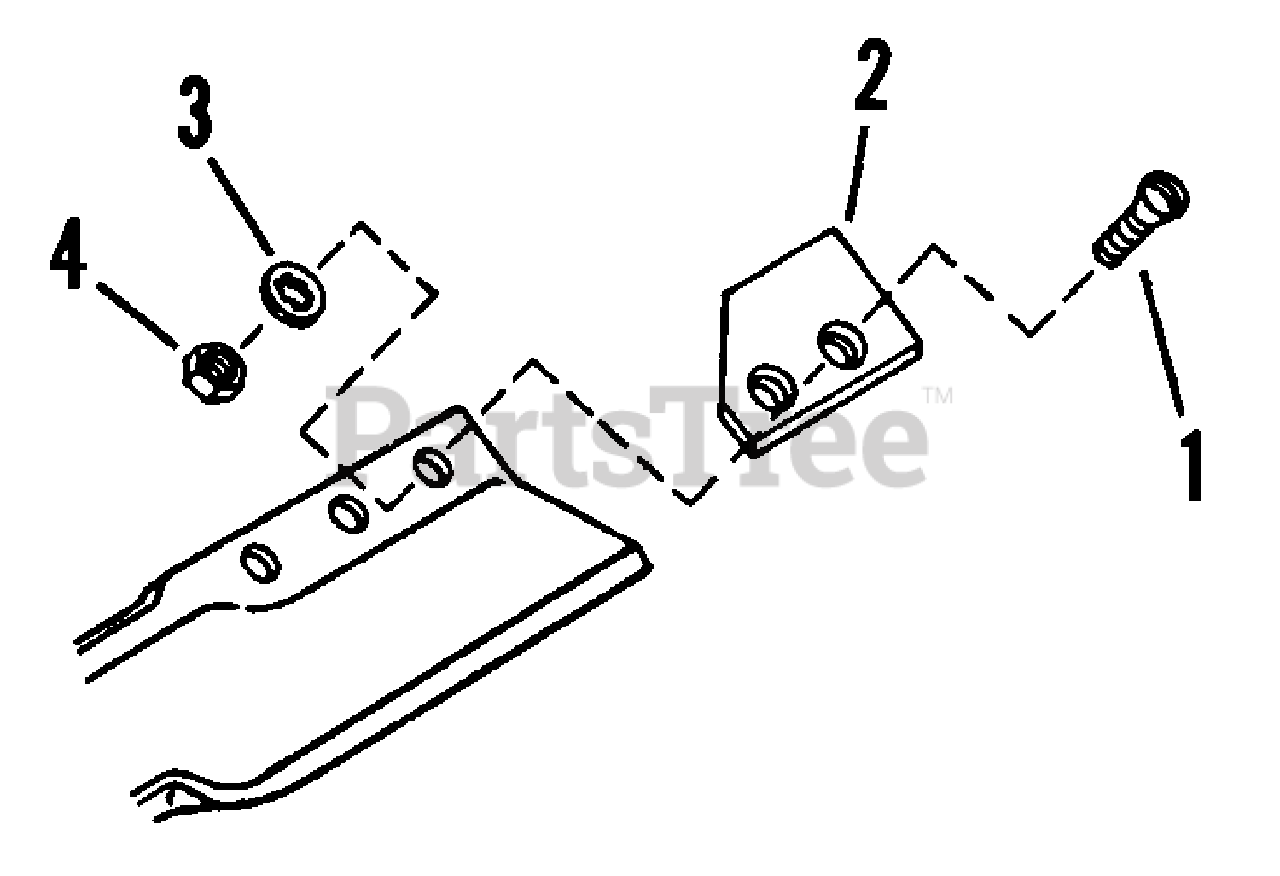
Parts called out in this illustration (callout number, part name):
1	SCREW, OHMS, 5/16-24 X .656 PH & O
2	AIR LIFT, 21" Blade
3	WASHER, Internal Tooth Lock, 5/16
4	NUT, Hex, 5/16-24 GR5 YZ
